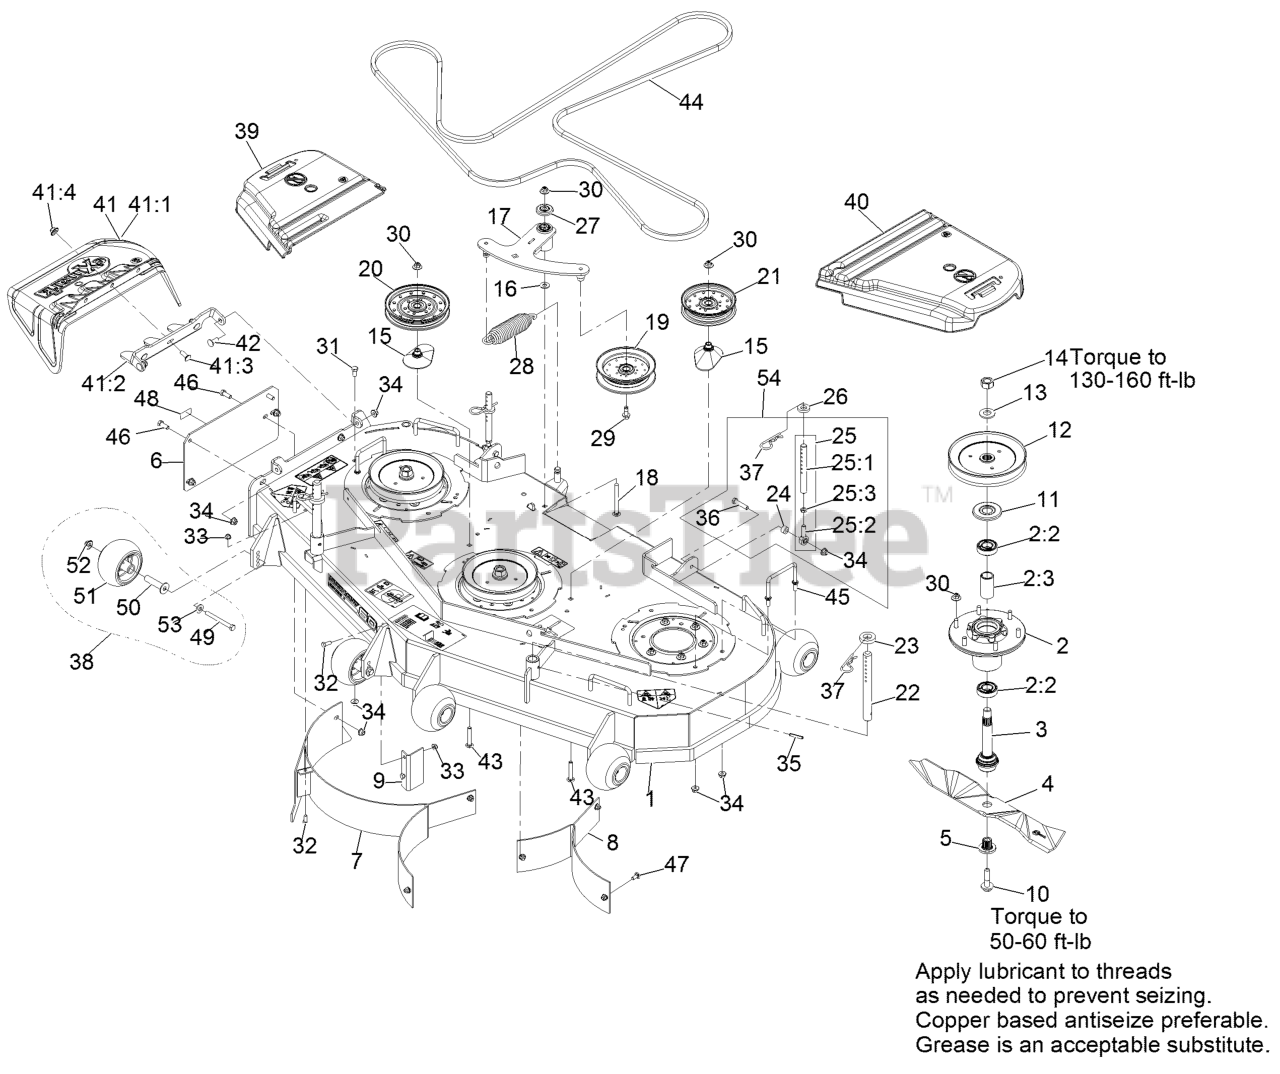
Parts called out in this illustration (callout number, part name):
1	ASM, DECK W/ DECALS, 60"
2	ASM-CUTTER HSG WITH BEARINGS
2:2	BEARING-BALL
2:3	SPACER-BEARING
3	ASM-SPINDLE AND SEAL
4	Blade-Extreme 2, 20.50"
5	BUSHING,SPLINED
6	PLATE-MULCH COVER, 604
7	BAFFLE WLD RH MULCH
8	XREF 1-632948-03 (EXMARK)
9	BAFFLE,BLOCKER MK604
10	SCREW,SEMS 1/2-20 X 2.19
11	GUARD,BEARING TOP .989
12	SHEAVE,BLADE DRIVE 7.25
14	NUT-HEX
15	SPACER-PULLEY
16	WASHER-FLAT
17	ASM, DECK IDLER
18	SCREW-CARR
22	ROD,DECK SUPPORT
23	SPACER-DECK SUPPORT
25:1	LINK,SUPPORT
25:2	BALLJOINT
25:3	NUT-HJ
27	GUARD-TOP
28	SPRING-EXTENSION
29	SCREW-HFH
30	Nut-Nyloc 3/8-16 Flg
31	SCREW-HH
32	SCREW-HH
33	NUT-HF, NI
34	NUT-HF, NI
36	SCREW-HH
37	PIN,HAIR COTTER
38	KIT, ANTI-SCALP ROLLER
39	COVER-BELT, RH
40	COVER-BELT, LH
41	ASM,DISCHARGE CHUTE
41:1	CHUTE,DISCHARGE
41:2	BRACKET,DISCHARGE CHUTE
41:3	SCREW-CARR
41:4	Nut-Nyloc 3/8-16 Flg
42	SCREW-CARR
43	BOLT-CARR, SHORT NECK
44	BELT, DECK DRIVE
45	WIREFORM-COVER
46	SCREW-HH
47	BOLT-CARR
48	Decal-Patent Ttco.Com
49	SCREW-HH 3/8-16 X 3 3/4 GR 8
50	AXLE, ROLLER
51	ROLLER-SCALP, ANTI
52	Nut-Nyloc 3/8-16 Flg
53	WASHER-BELLEVILLE
54	KIT,SUPPORT LINK W/PIN
